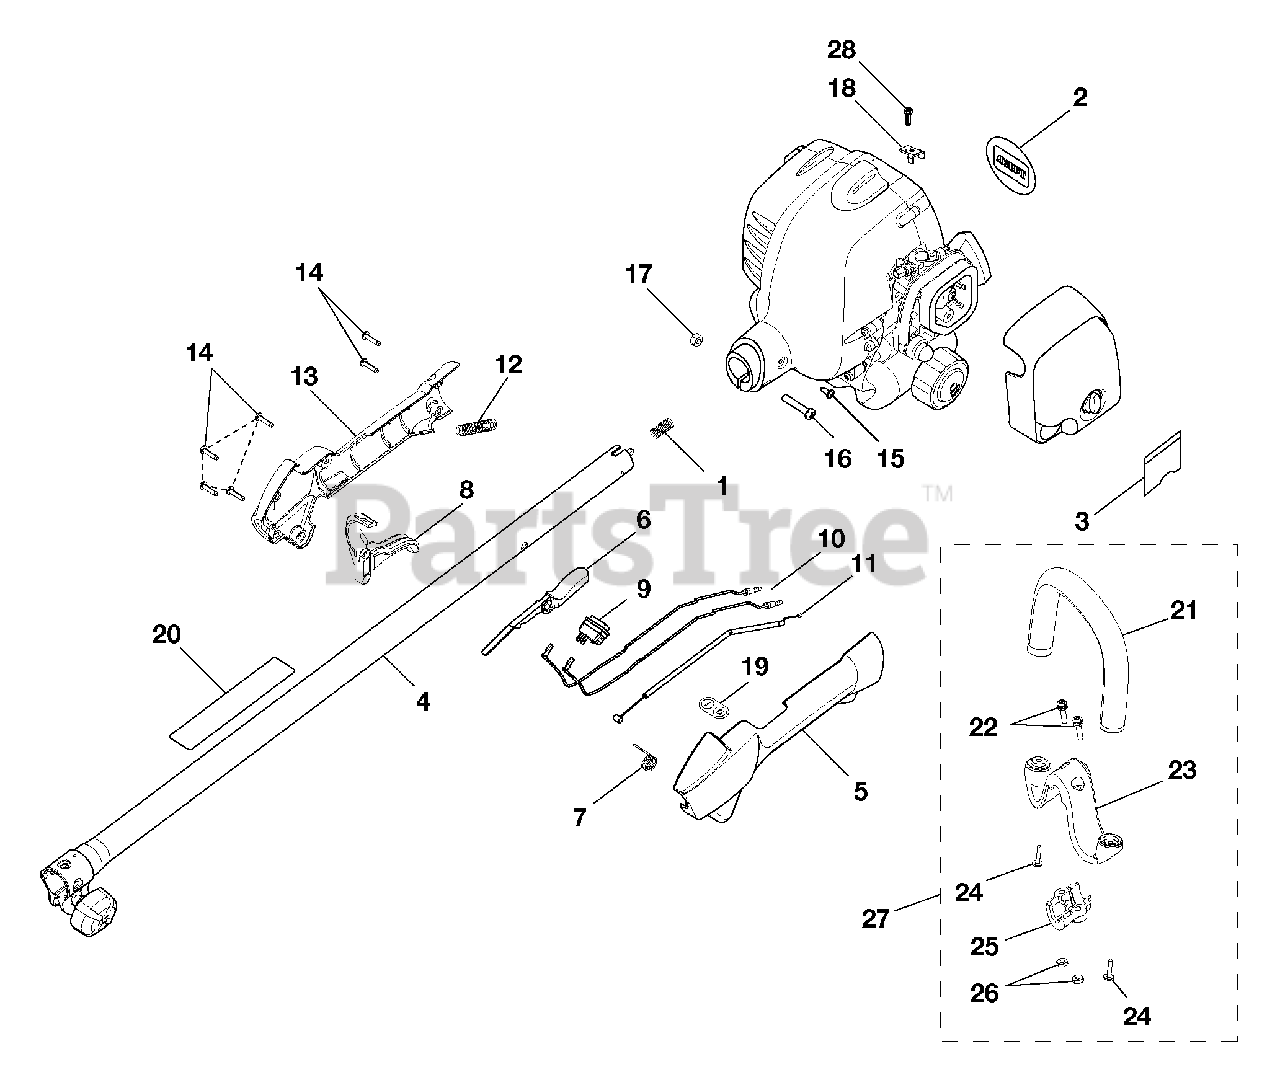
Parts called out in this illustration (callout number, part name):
1	COMPRESSION SPRING
2	LOGO PLATE
3	LOWER START LABEL
4	UPPER SHAFT ASSEMBLY
5	REAR HANDLE SUPPORT
6	LOCK-OFF BUTTON
7	TRIGGER SPRING
8	TRIGGER
9	SWITCH WITH DUST SHIELD
10	LEAD
11	CABLE, THROTTLE
12	CORRUGATED TUBE
13	REAR HANDLE COVER
14	SCREW (M4 X 16 mm)
15	SCREW (#8-16 X 1/2 in. TRI-LOBULAR)
16	SCREW (M6 X 1-30 mm)
18	THROTTLE CABLE CLAMP
19	ON/OFF LABEL
20	WARNING LABEL
21	ASSIST HANDLE W/GRIP
22	SCREW (#12-24 X 1 in. SEMS)
24	SLOTTED TORX SCREW
25	CLAMP
26	HEX NUT (12-24)
27	ASSIST HANDLE ASSEMBLY
28	SCREW (M4 X 16 mm)
